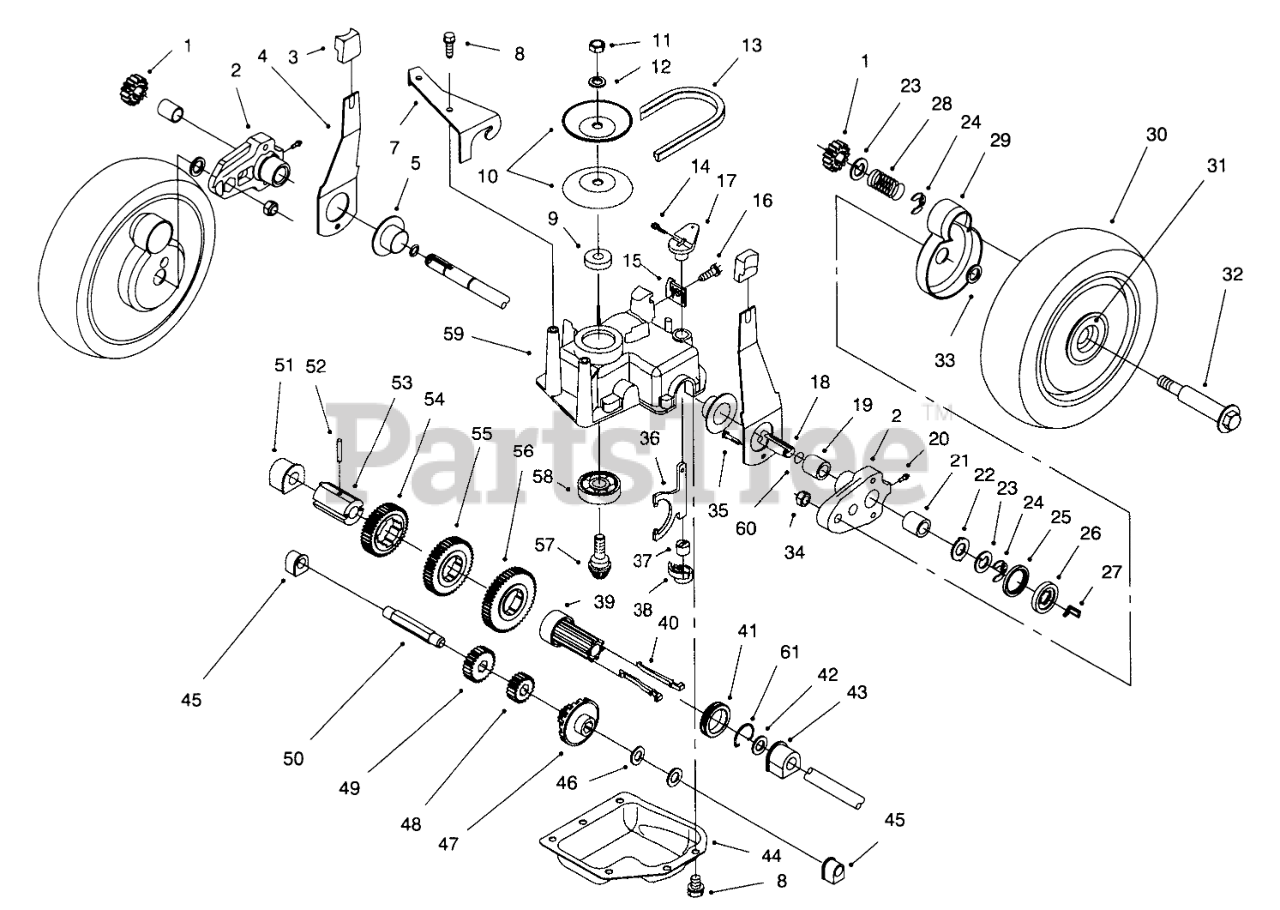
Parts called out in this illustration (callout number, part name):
1	GEAR-PINION
2	Pivot Arm Assembly (Incl. Ref # 19, 20, & 21)
3	KNOB-ARM
4	SPRING ARM ASM SP
5	CAP-END
7	Bracket-Guide
8	SCREW-HWHTF
9	SPACER
10	Pulley Half
11	NUT-HEX
12	WASHER-FLAT
13	V-BELT E
14	PIN-COTTER
15	CLAMP-CABLE
16	SCREW-HWHTF
17	LEVER-SHIFT
18	SHAFT-OUTPUT
19	BUSHING
20	FITTING-GREASE
21	BEARING-ROLLER
22	WASHER-ARM, PIVOT
23	WASHER-THRUST, KEYED
24	RING-CLIP, LOCKING
25	RING-FRICTION
26	WASHER-CLUTCH
27	KEY-ROCKING, LH
28	SPRING-COMPRESSION
29	COVER-WHEEL
30	Wheel-Tire & Gear Ass-y (Incl. Ref. # 31)
31	BUSHING
32	BOLT-WHEEL
33	SPACER-COVER, WHEEL
34	NUT-LOCK
35	SCREW-HWH
36	YOKE-SHIFT
37	BUSHING-YOKE
38	RETAINER-FORK, SHIFT
39	SLEEVE-KEY, SHIFT
40	KEY-SHIFT
41	COLLAR-SHIFT
42	WASHER-PLAIN
43	BUSHING-OUTPUT
44	Cover-Gearcase
45	BUSHING
46	WASHER-THRUST
47	Gear-Bevel
48	PINION-20T
49	PINION-25T
50	SHAFT-INTERMEDIATE
51	BUSHING
52	PIN-SPRING
53	SLEEVE-GEAR
54	GEAR-39T
55	GEAR-44T
56	GEAR-49T
57	Gear-Pinion
58	BEARING-BALL
59	CASE-GEAR, UPPER
60	O-RING
61	CLIP-SPRING
